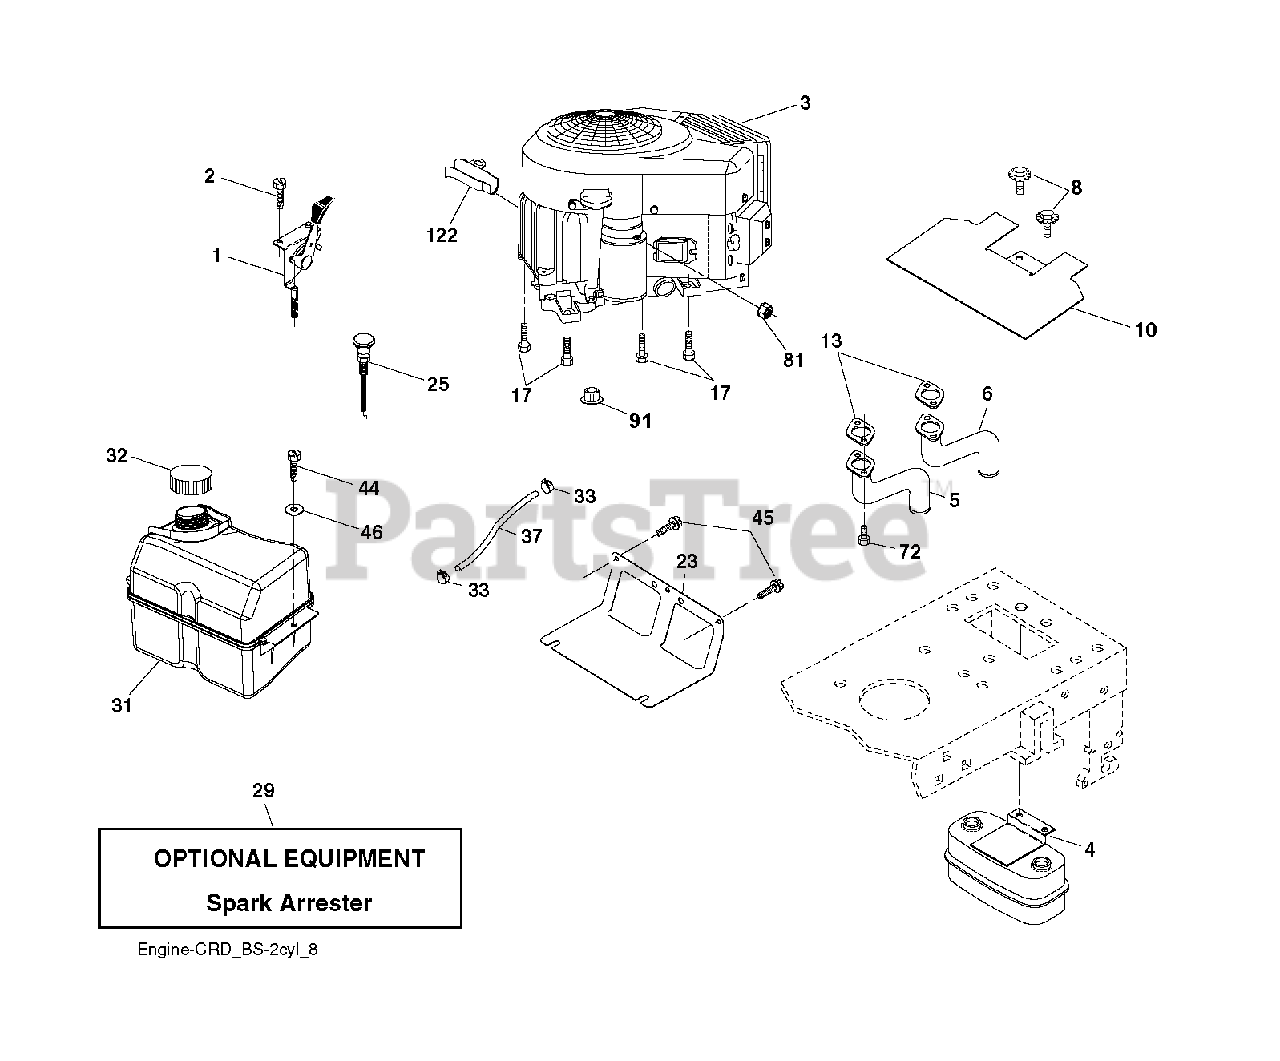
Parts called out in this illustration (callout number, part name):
1	THROTTLE CABLE
2	SCREW.#10 X 0.750.BOS THREAD
4	MUFFLER.TWIN.CYL.LOW.TONE
5	EXHAUST TUBE RH
6	TUBE MANIFOLD LH
8	BOLT, 5/16-18 X 1 3/4
10	RP SHIELD HEAT MUFFLER
13	GASKET.MUFFLER
17	SCREW.3/8-16
23	SHEILD.BROWNING.DBR.GUARD
25	CONTROL CHOKE
29	ARRESTER SPARK (OPTIONAL)
32	CAP ASM.FUEL.2.25"FR.
33	HOSE CLAMP
37	LINE.FUEL.20
44	SCREW HEXWSHR 1/4-20X3/4
45	SCREW, 3/8-16X3/4
72	SCREW.SOCKET.HEAD.5/16-18
81	NUT
91	BUSHING.1.375OD
122	EXTENSION DRAIN OIL
